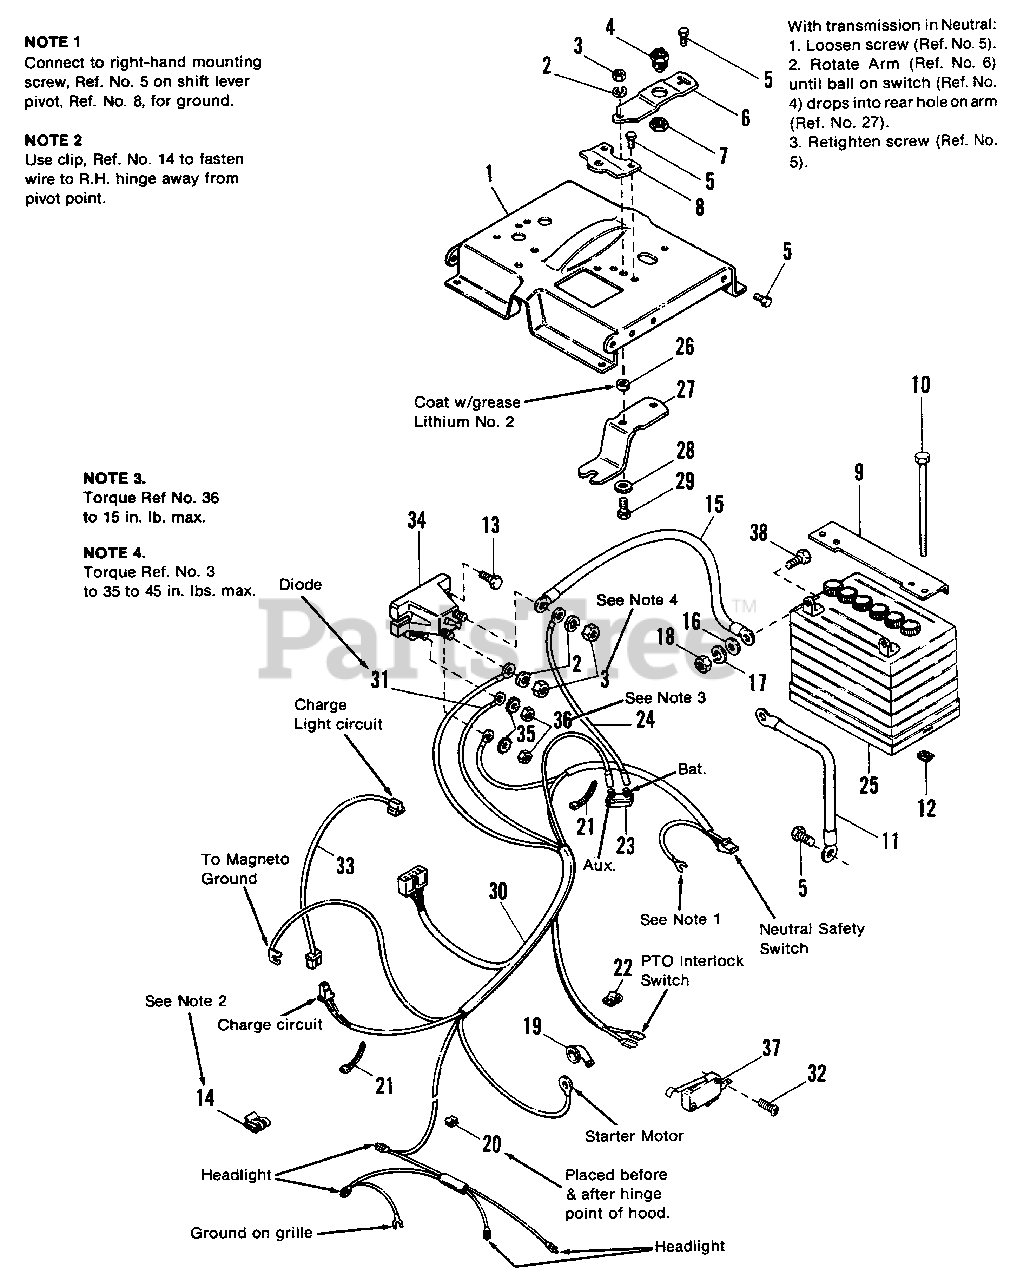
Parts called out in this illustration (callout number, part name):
1	SUPPORT, Frame
2	LOCKWASHER, 5/16
3	NUT, Hex, Full, 5/16-18
4	SWITCH, Interlock
5	SCREW, Hex, Taptite, 1/4-20 x 3/8
6	BRACKET, Switch
7	LOCKNUT, Hex, 9/16-18
8	PIVOT, Shift Lever
9	HOLD DOWN, Battery
10	CAPSCREW. Hex, 1/4-20 x 7-1/2
12	NUT, Retaining, 1/4-20
13	SCREW, Taptite, 1/4-20 x 3/4
14	CLIP, Wire
16	WASHER, Plain, 1/4
17	LOCKWASHER, 1/4
18	NUT, Hex, Full, 1/4-20
19	COVER, Terminal
20	CLIP, Wire
21	TIE, Self-Locking
22	CLIP, Speed
23	BREAKER, Circuit
25	BATTERY, 39 amp.
27	LEVER, Switch
29	CAPSCREW. Hex, 5/16-18 x 1
30	HARNESS, Lower (Includes Ref. No. 31)
31	DIODE ASSY.
32	SCREW, Taptite, #5-40 x 3/4
33	WIRE ASSY. (Used on 6216 & 6218 Only)
34	SOLENOID
35	LOCKWASHER, Ext. #10
36	NUT, Hex, #10-32
37	SWITCH, P.T.O. Interlock
38	CAPSCREW, Hex, 1/4-20 x 3/4
